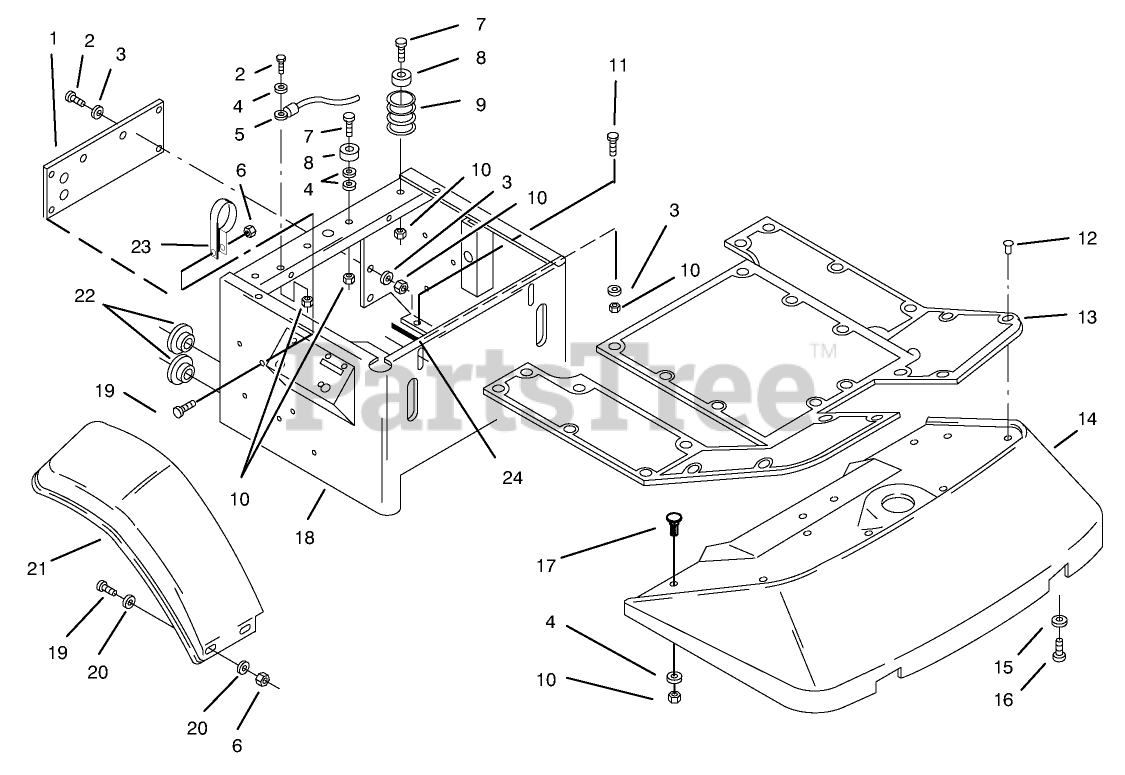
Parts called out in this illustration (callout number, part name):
1	Cover
2	SCREW-HH
3	WASHER-PLAIN
4	WASHER-FLAT
5	Cable-Seat (Ref.)
6	NUT-LOCK, NI
7	SCREW-HH
8	BUMPER
9	SPRING
10	NUT-LOCK, NI
11	SCREW-HHF
12	RIVET .25 PLASTIC
13	Black Mat
14	Floor Pan
15	WASHER-LOCK
16	SCREW-HWHTF
17	BOLT-CARR
18	SUPPORT-SEAT W A R
19	SCREW-HH
20	WASHER-FLAT
21	Fender RH
22	BUSHING-NYLON 1.500
23	CLAMP-R
24	EDGE TRIM
